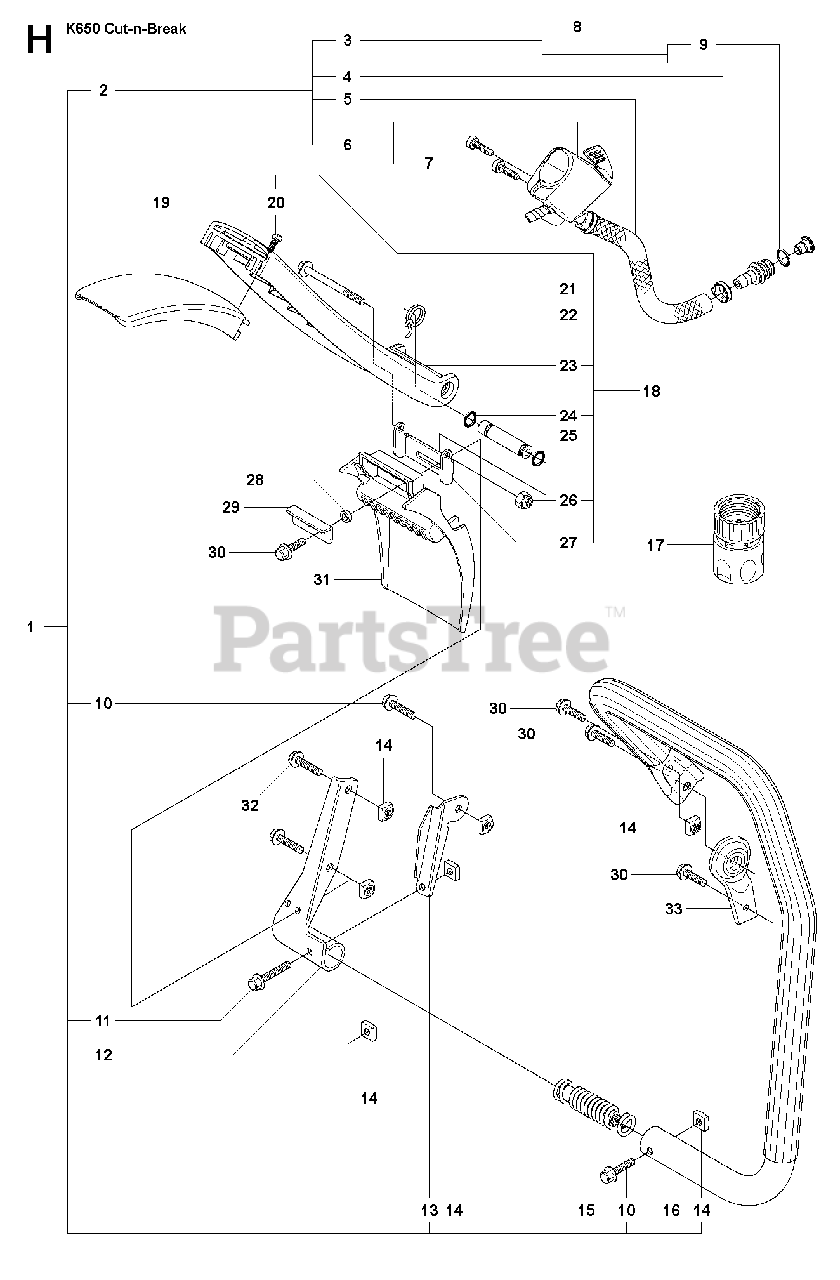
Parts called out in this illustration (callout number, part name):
1	HANDLEIncl. 2, 10 - 16
4	HOSE CLAMP
5	HOSEL=280mm
9	O-RING
10	SCREW EHHFM
17	COUPLER
18	SPRAY GUARDIncl. 19 - 27
20	SCREW CRPANT
33	ANTIVIBRATION ELEMENT
